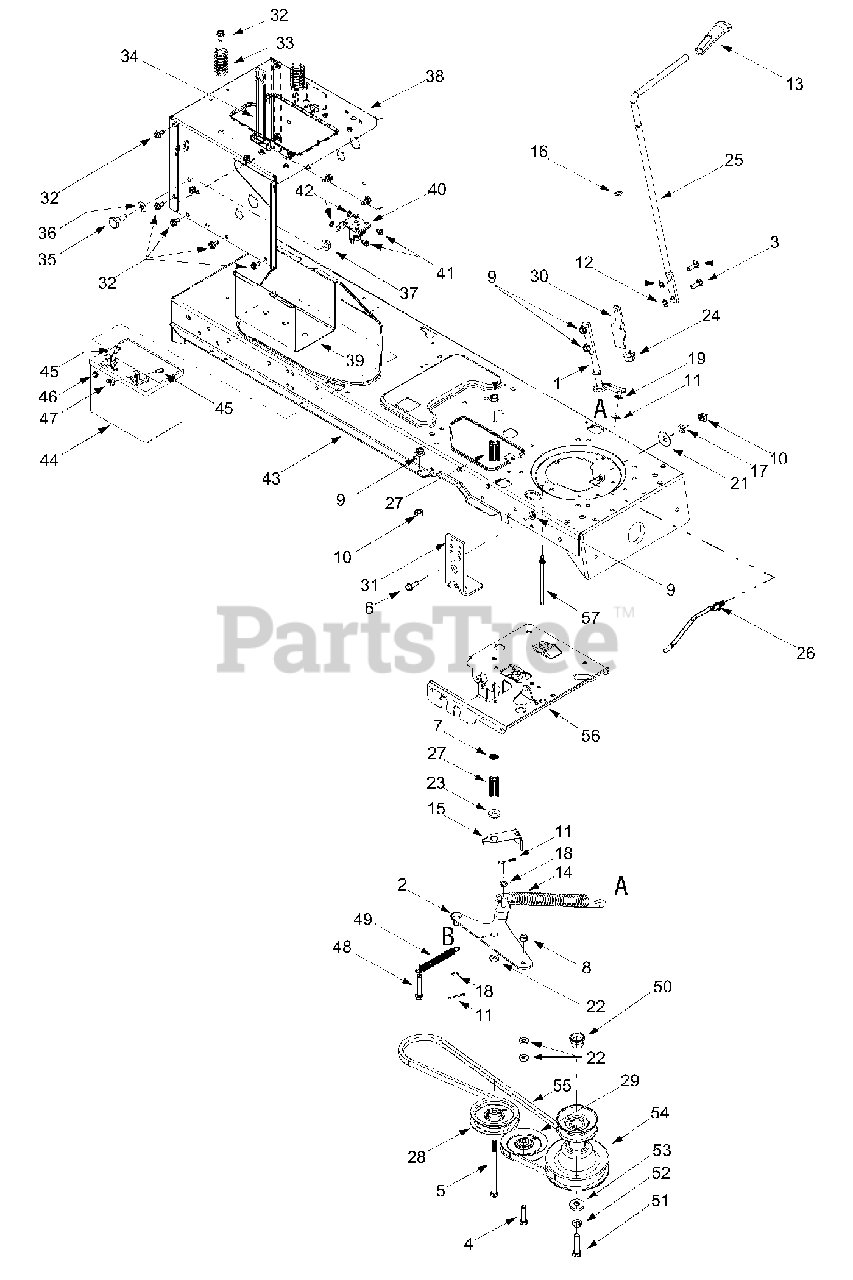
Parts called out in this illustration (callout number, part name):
1	PTO Engage Lever Assembly
4	Hex Cap Screw, 3/8-16 x 1.5
5	Hex Cap Screw, 3/8-16 x 5.5
6	Hex Head Washer Screw, 5/16-18 x .875
7	Push Nut, 3/8
8	Flange Lock Nut, 3/8-16
9	Flange Lock Nut, 5/16-18
10	Hex Nut, 5/16-18
11	Cotter Pin, 1/8 x 1.25
12	Speed Nut, .3125
13	PTO Knob
14	Extension Spring, .75 x 6.75
15	Belt Guard
16	Flat Washer, .510 x .750 x .033
17	Lock Washer, 5/16
18	Flat Washer, .385 x .62 x .063
19	Flat Washer, 5/16
20	Flat Washer, .406 x .875 x .059
21	Bell Washer, .39 x 1.13 x .062
22	Flat Washer, .407 x .812 x .135
23	Shoulder Spacer, .380
24	Hex Split Flange Bearing, .5
26	Belt Keeper Rod
27	Spacer, 3/8 x 1.54
28	Idler Pulley, 3.5
29	Idler Pulley, 4.0
32	Self Tapping Screw, 5/16-18 x .625
33	Compression Spring, 1.28 x 3.5
34	Battery Strap
35	Shoulder Screw, .625 x .5, 7/16-20
36	Bell Washer, .45 x 1.0 x .062
37	Flange Lock Nut, 7/16-20
41	Self Tapping Screw, 1/4-20 x .5
42	Lock Washer, 1/4
45	Hex Cap Screw, 1/4-20 x .62
46	Hex Sems Nut, 1/4-20
47	Wing Nut, 1/4-20
48	Extension Spring, .50 x 5.0
49	Hex Cap Screw, 5/16-18 x 1.75
50	Spacer Cup
51	Hex Head Cap Screw, 7/16-20 x 1.25
52	Lock Washer, 7/16
53	Flat Washer, .450 x 1.25
54	Engine Pulley, 3.56 OD x 5.56
55	PTO Belt
57	Keeper Pin, 5/16 x 4.75
58	Belt Guard
